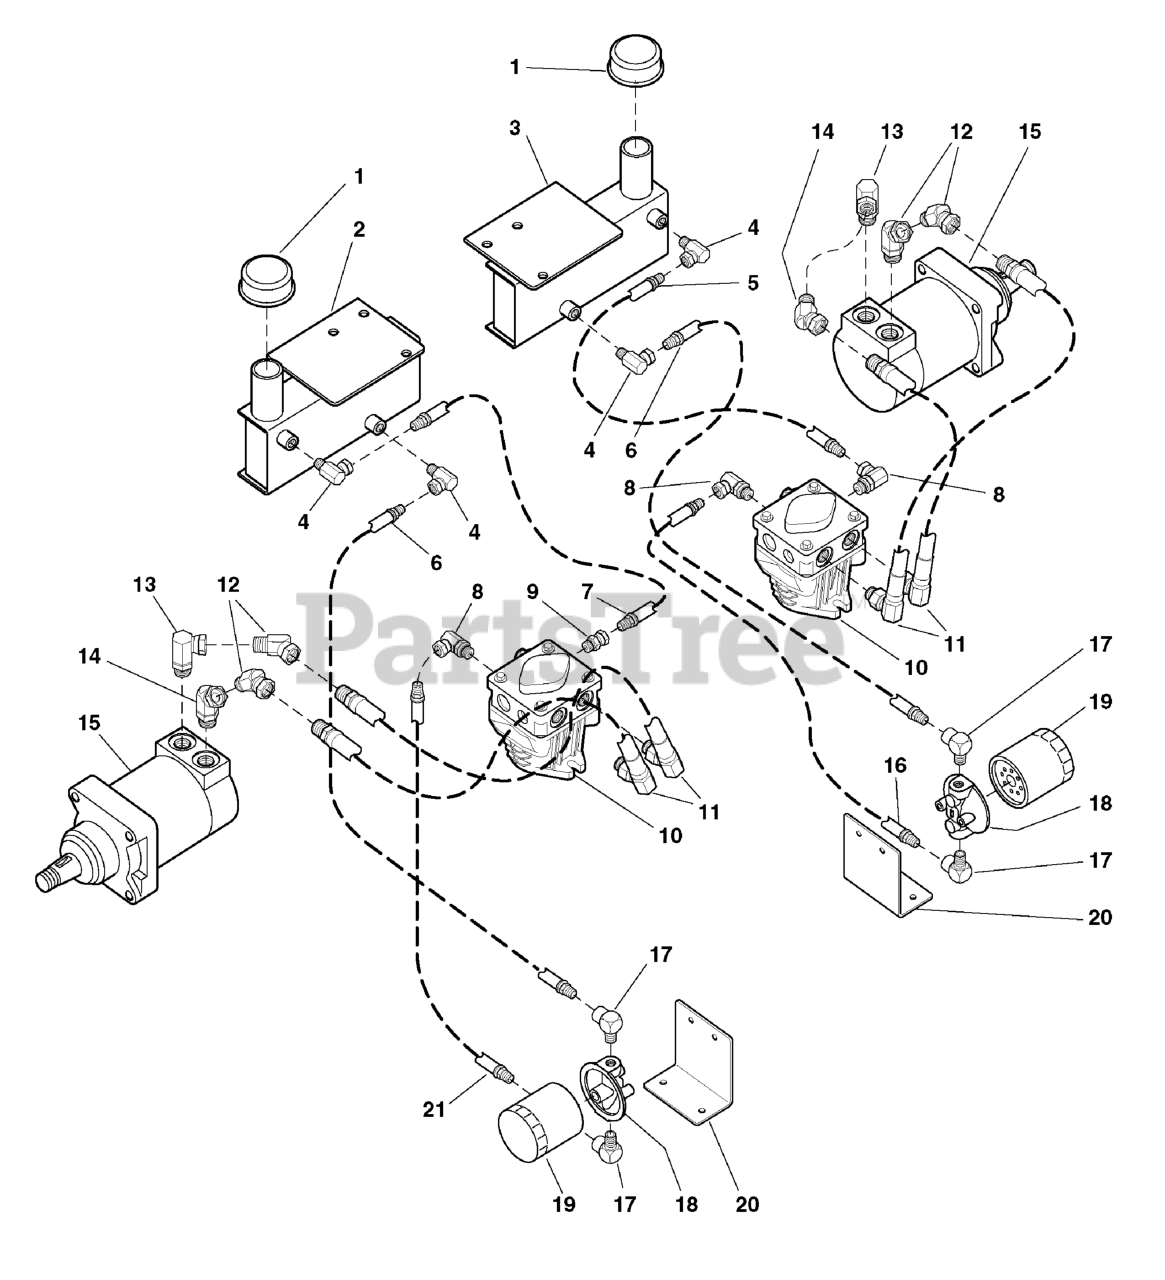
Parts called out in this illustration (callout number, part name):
1	BREATHER
2	HYDRO TANK, LH
3	HYDRO TANK, RH
4	FITTING, 1/4" NPT 90 Degree Swivel
5	HOSE ASSEMBLY-24"
6	HOSE ASSEMBLY-13"
7	HOSE ASSEMBLY-14"
8	FITTING, O-Ring, 90 Deg. Swivel
9	FITTING, 9/16" O-Ring Straight Swivel
10	HYDRAULIC PUMP
12	FITTING, 1/2 NPT, 45 Deg. Swivel
13	FITTING, O-Ring, 90 Deg. Swivel
14	FITTING, 7/8" O-Ring 45 Degree Swivel
15	HYDRAULIC WHEEL MOTOR
15	KEY
15	NUT & COTTER PIN
16	HOSE ASSEMBLY-18"
17	FITTING, 1/4 NPT, 90 Deg.
18	FILTER HEAD
19	FILTER
20	MOUNT, Filter Head
21	HOSE ASSEMBLY-16"
